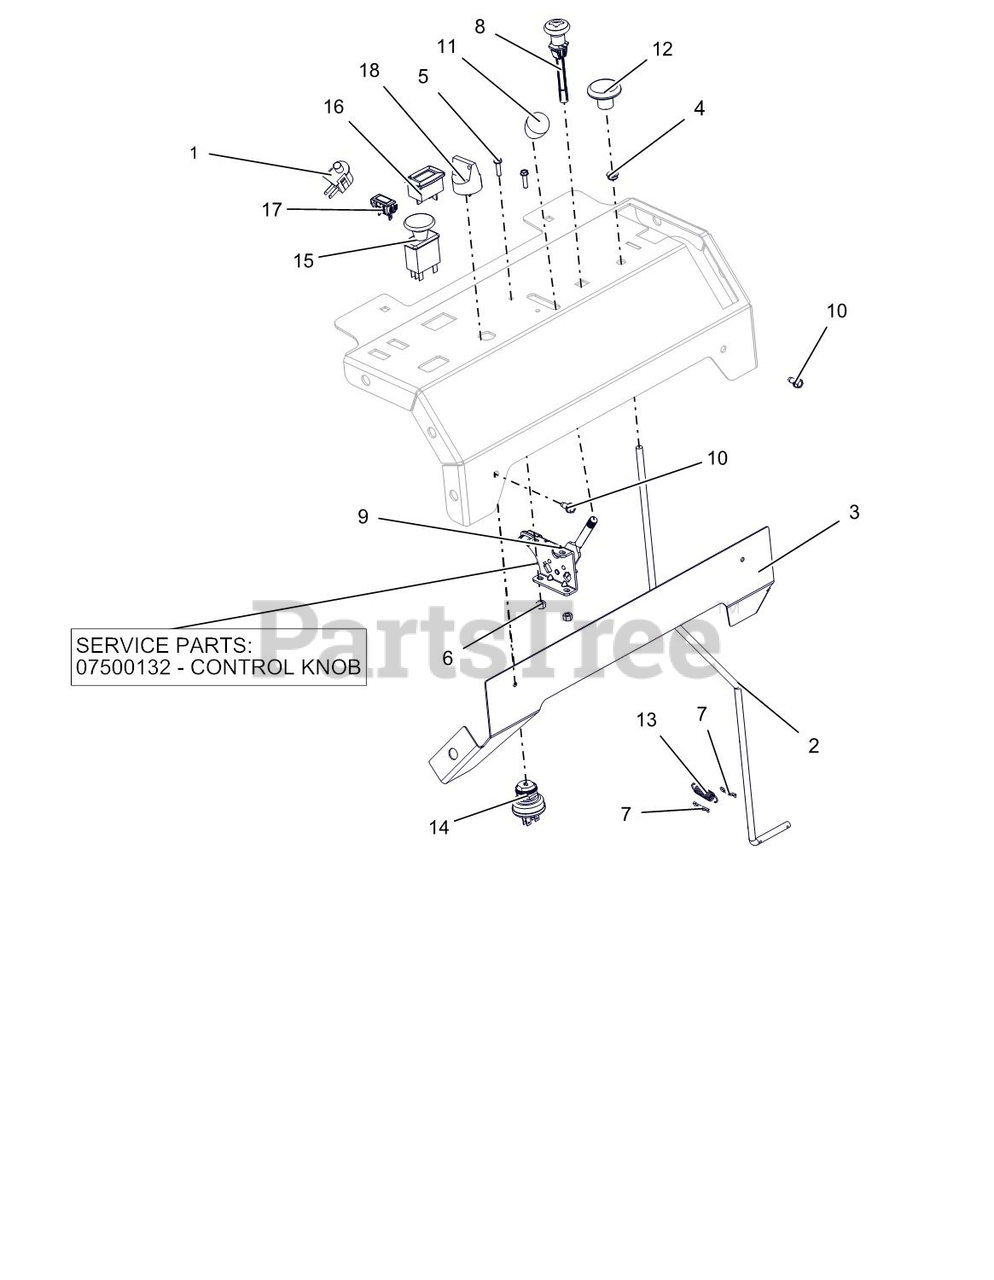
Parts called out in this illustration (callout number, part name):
1	SWITCH- SNAP MTG N.O.
2	WIREFORM, TRAILER LOCK
3	PLATE, FRONT BACKER
4	BUSHING, POLYLINER-.38 SNAPIN
5	@SCR-MCH 10-24X.75 HWH YWZC
6	@NUT-LK-NYL 10-24 W/INSRT YWZC
7	PIN-HAIR, ENDRIES #25 YWZC
8	CABLE, CHOKE (SNAP IN)
9	KNOB-CONTROL-BLACK .38-16X.50
9	CABLE, PRO-CONTROL
10	SCR-TAP .25-20X.50 HWH TR YWZ
11	KNOB-CONTROL-BLACK .38-16X.50
12	KNOB, PUSH-PULL .312-18
13	SG-TENS .048X.44X1.75 WLD 9
14	SWITCH, IGNITION
15	SWITCH, CLUTCH
16	METER, HOUR W/MAINTENANCE
17	LIGHT,INDICATOR
18	KEY, W/ SHIELD
